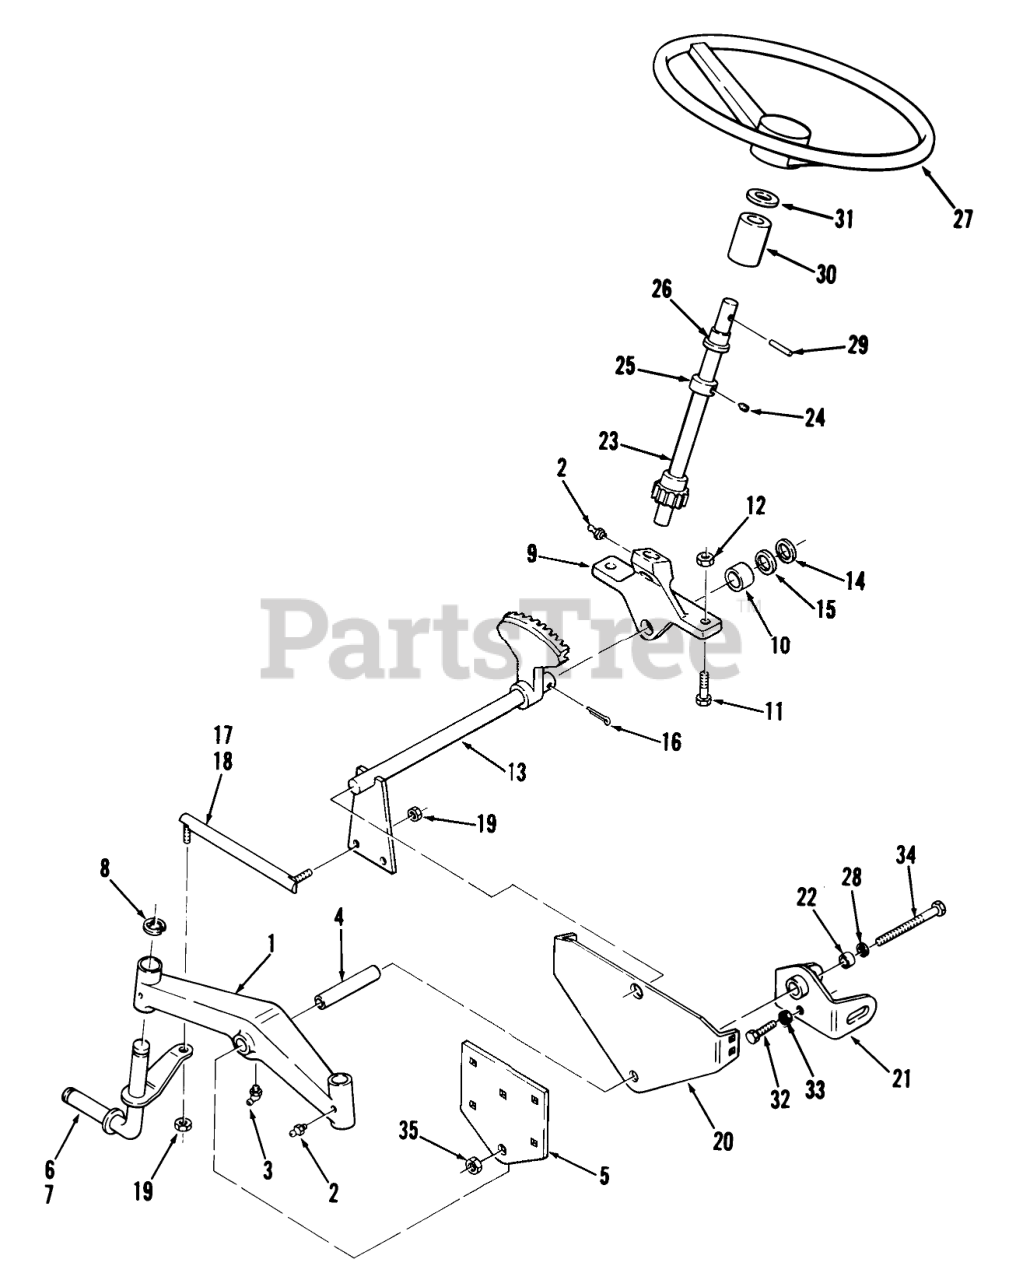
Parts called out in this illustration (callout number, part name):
1	AXLE-FRONT R
2	Zerk
3	FITTING-GREASE
4	SPACER-AXLE
5	Plate-Front Axle
6	Assy-Front Spdl RH
7	Assy-Front Spdl LH
8	Snap Ring
9	Support
10	BEARING-BRONZE
11	Bolt
12	Nut
13	ASSY-STRG SHFT LO R
14	WASHER-SHIM
15	WASHER
16	PIN-4
17	25LL JOINT ASSY R R
18	BALL JOINT ASSY L R
19	NUT-6
20	Support-Front Axle
21	Front Hanger (Mower)
22	BUSHING
23	ASSY-STRG SHFT-UP R
24	SCREW-SET
25	Collar
26	BEARING
27	STEERING WH 13" PLAS
28	Washer
29	Pin-Roll
30	COLLAR
31	WASHER-BOWED
32	SCREW-HH
33	Nut
34	Bolt 1/2-13 X 5
35	Eslok Nut
